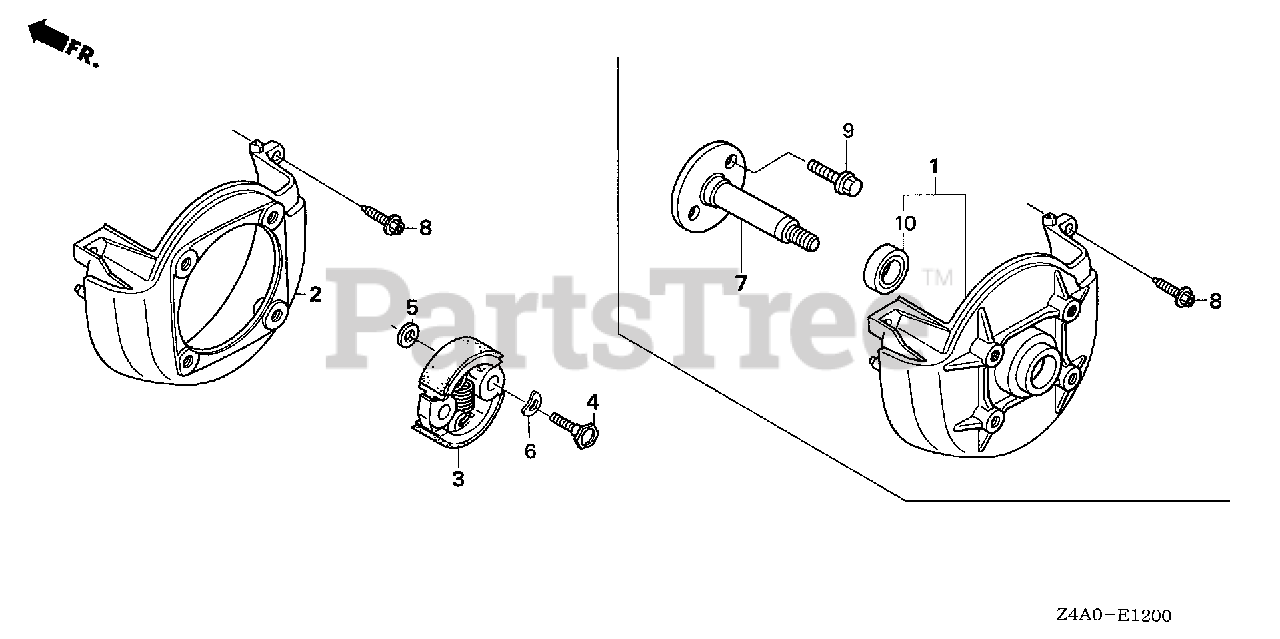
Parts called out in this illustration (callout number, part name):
2	COVER, FAN
3	CLUTCH ASSY.
4	BOLT, CLUTCH (6MM)
5	WASHER, CLUTCH (6X15)
6	WASHER, WAVE (8MM)
8	BOLT, SOCKET (5X20)
